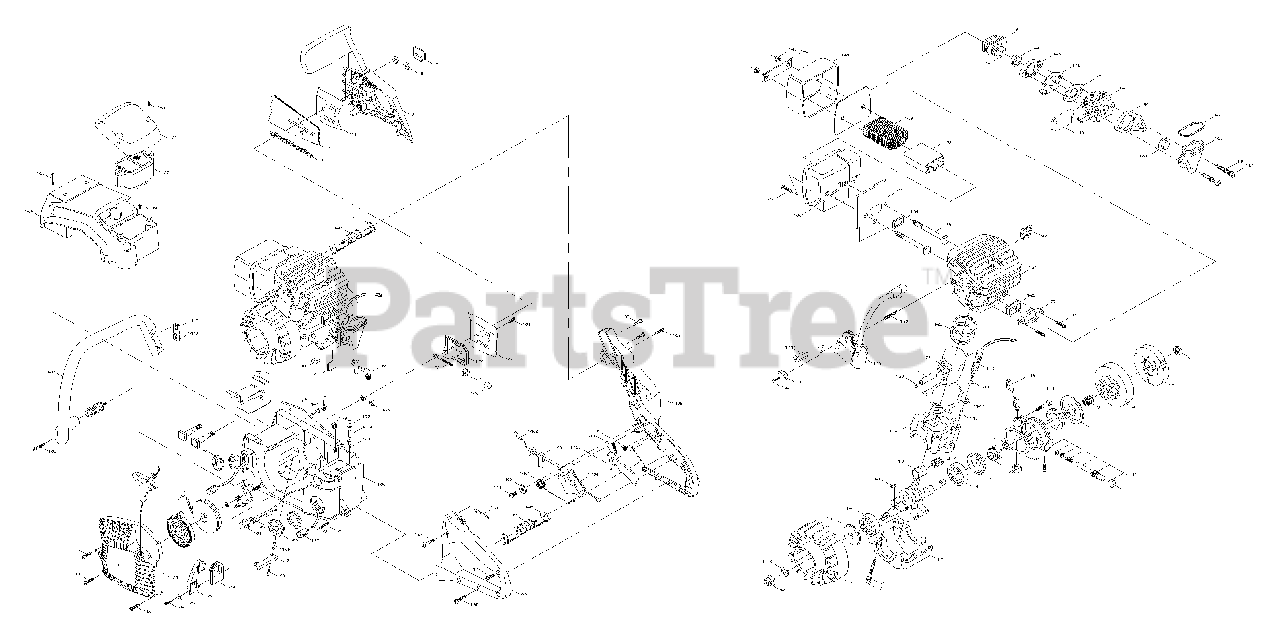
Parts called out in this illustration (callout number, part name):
1	POWERHEAD ASS'Y
1-7	CRANKCASE LOWER
1-9	C'SHAFT/C'ROD ASS'Y
1-12	PUMP ASS'Y
1-13	CONNECTOR
1-15	FITTING, PULSE LINE
1-16	CRANKCASE UPPER
1-18	CLAMP, WIRE HOSE
1-19	CONDUIT, FLEX
1-23	RING, PISTON
1-25	SPARK PLUG
1-29	IGNITION ASS'Y
1-31	CONTACT, CROUNT
1-36	MUFFLER BODY ASS'Y
1-41	COVER, MUFFLER
1-42	LOCKPLATE
1-55	STARTER ASS'Y
1-58	PRECLEANER ASS'Y
1-59	BOOT, INTAKE
1-60	FUEL/OIL TANK ASS'Y
1-60-1	FILTER, OIL
1-61	PRIMER, REMOTE
1-66	CAP, FUEL
1-67	FILTER, FUEL
1-71	VALVE DUCKBILL
1-79	PLATE, BAR
1-80	PLATE, FLANGE
1-83	HANDLE ASS'Y
1-84	COVER ASS'Y
1-87	AIR CLEANER ASS'Y
1-90	CHOKE ASS'Y
1-91	ROD, CHOKE
1-93	ISOLATOR ASS'Y
1-94	CABLE ASS'Y
1-95	COVER ASS'Y, HANDLE
1-99	ISOLATOR ASS'Y
1-105	RELEASE. TRIGGER
1-106	LATCH, HIGH IDLE
1-108	FRAME, REAR
1-112	RETAINER, NUT
2	GEAR, WORM
6	DRUM SPRKT ASS'Y
7	CLUTCH ASS'Y
9	BOOT, CARB
12	CHAIN 72EB
15	CHAIN BRAKE ASS'Y
